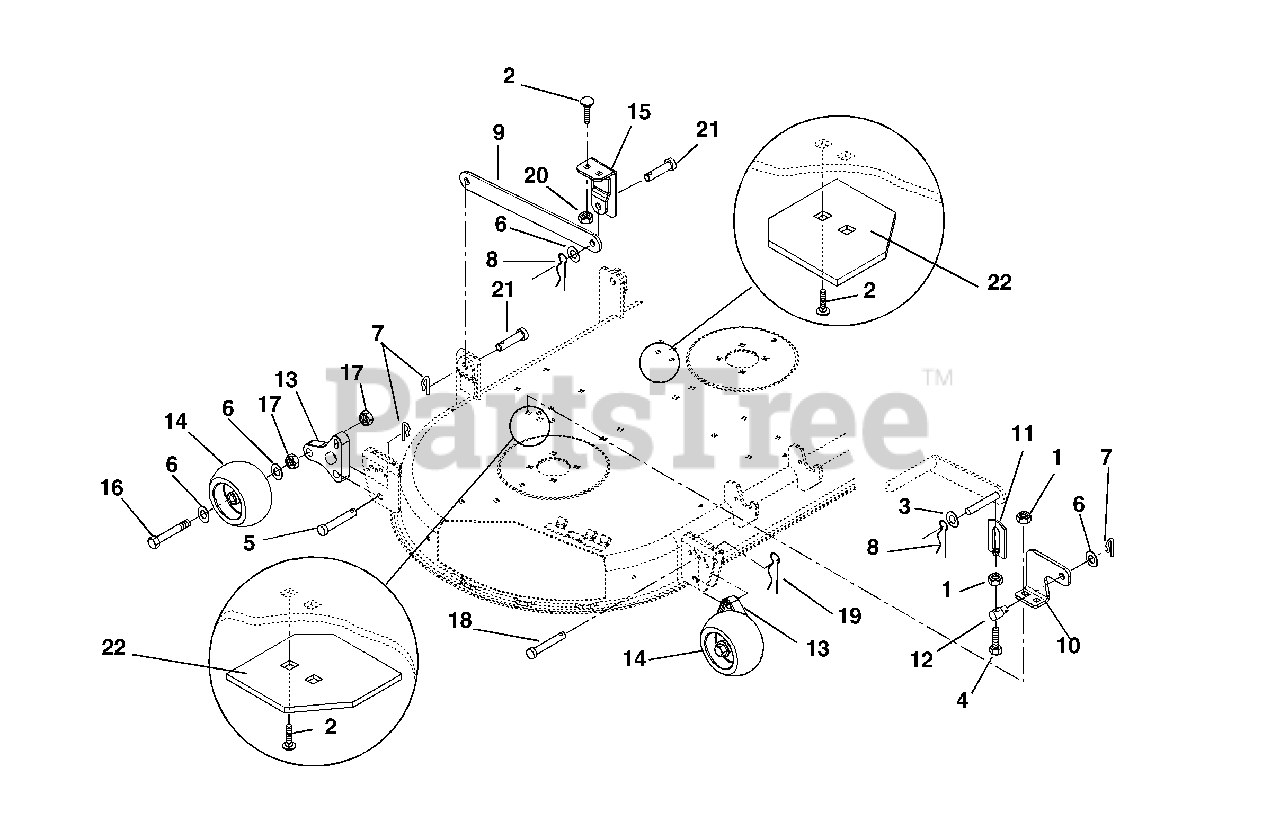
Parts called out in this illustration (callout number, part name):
1	@NUT-LK-CTR .38-16 YWZC
2	@BLT-RDHDSQNK .38-16X.75 G5YZ
3	@WSHR-FL-STL.563X1.38X.109YWZC
4	BLT-HEX .38-16X2.50 FTH YWZC
5	PIN-CLEV .50X1.38 YWZC
6	WSHR-FL-STL .505X.880X.072 YWZ
7	CLIP, SPRING
8	PIN-HAIR-EXT .12X.31X2.37 YWZC
9	LINK, LIFT
10	BRACKET, LIFT
11	WELDMENT, ADJUSTMENT LINK
12	TRUNNION
13	BRACKET, ROLLER ADJUST.
14	WHEEL 5 X 3
15	WELDMENT, DECK STOP BRACKET
16	@BLT-HEX .50-13X4.00 GR5 YWZC
17	NUT-LK-CTR-JAM .50-13 YWZC(ND)
18	PIN-CLEV .31X1.38 YWZC
19	PIN-HAIR INT .08X.18X1.18 YWZC
20	@NUT-LK-NYL .38-16 YWZC
21	PIN-CLEV .50X1.00 YWZC
22	REINFORCEMENT, DECK LIFT
